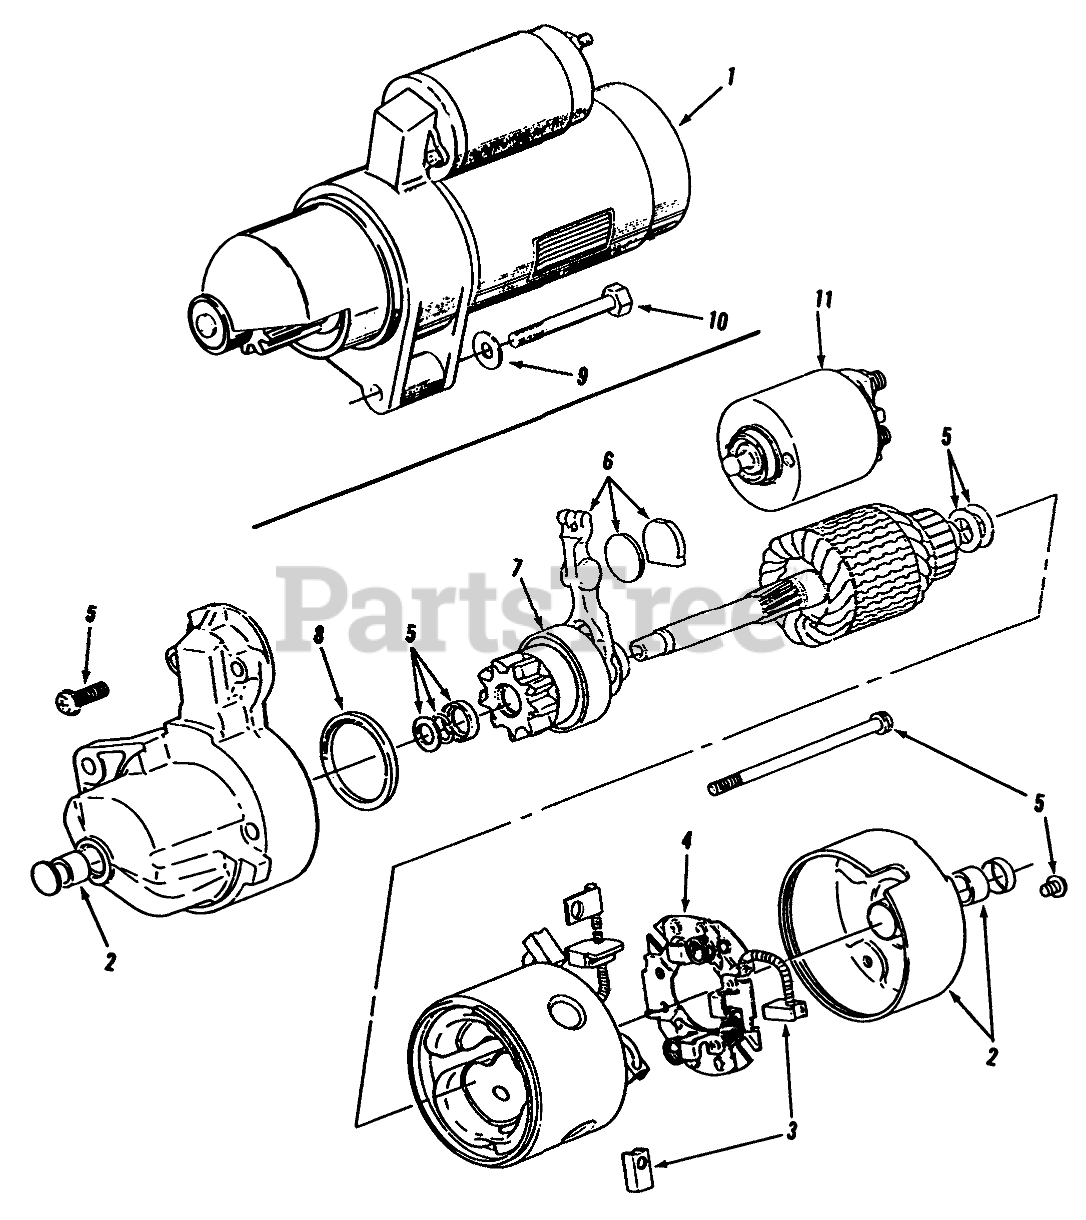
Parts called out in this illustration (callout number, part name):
1	Starter Assy
2	Bushing Kit (Includes Frt. Bushing and Rear Cap w/ Bushing)
3	Brush Kit (Includes Positive Brush (2) and Negative Brush w/ Pigtail)
4	Brush Holder (Includes Brush Holder w/ Negative Brush)
5	Hardware Kit (Includes Solenoid Screws (2), Brush Holder Screws (2Thru Bolts (2), Armature Shims (2), Pinion Stop Collar and Pinion Retaining Ring)
6	Starter Shim Lever Kit (Includes Shim Lever, Wear Plate and Rubber Plug)
7	Starter Clutch (Includes Pinion Gear w/Clutch)
8	Dust Seal
9	Washer
10	Bolt
11	Starter Solenoid Kit (Includes Solenoid, Spring and Plunger)
